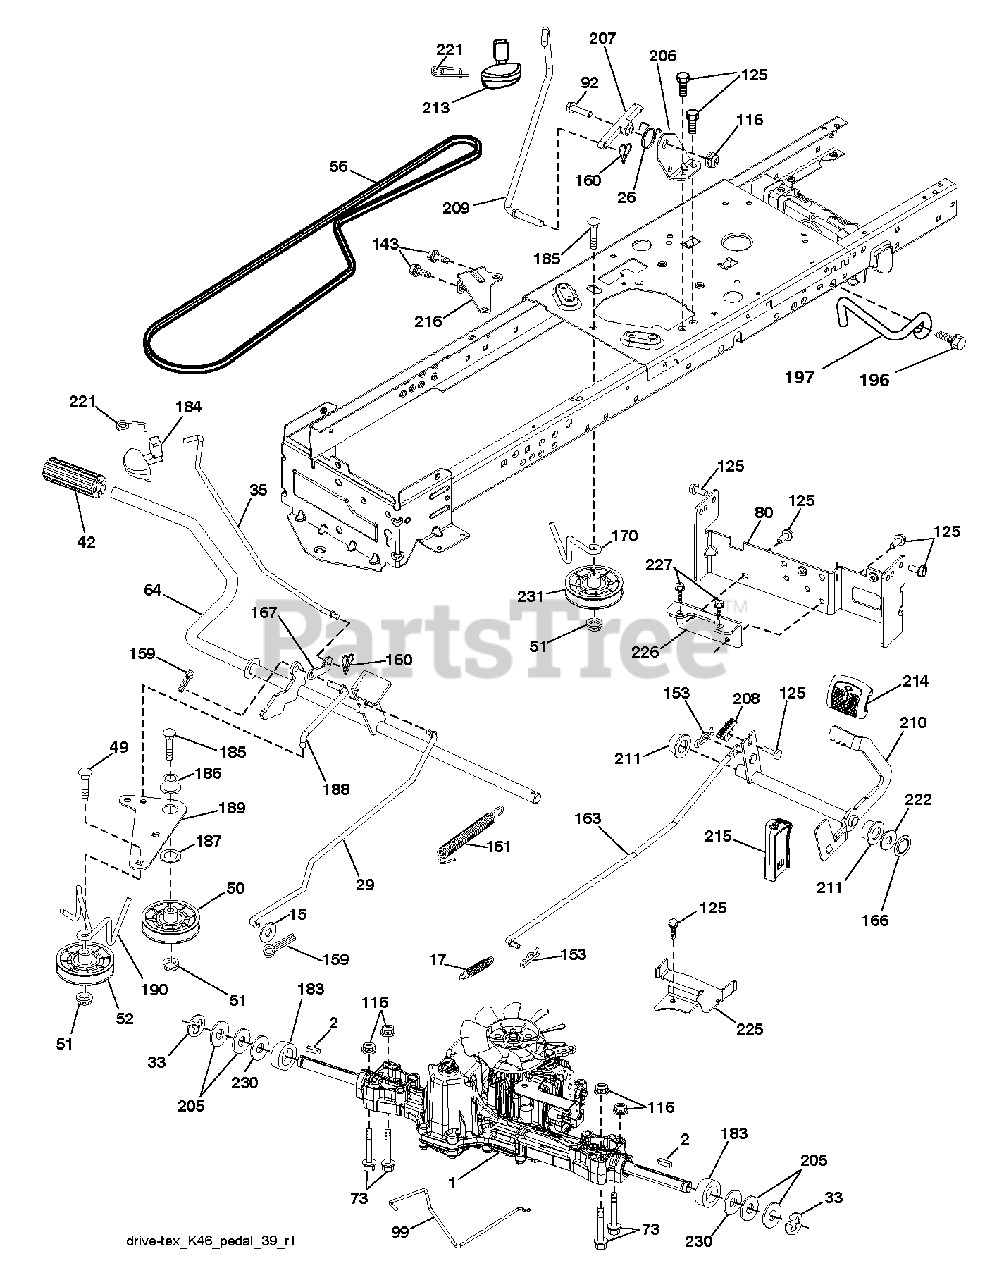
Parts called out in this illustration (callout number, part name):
2	SQUARE KEY
15	WASHER
17	SPRING.BRAKE.K46.GREEN
26	SPRING.RETURN.CRUISE
29	ROD.BRAKE.K46
33	E-RING LT
35	ROD.BRKAE.PARKING.STEALTH
50	IDLER.FLAT.910.OFFSET
52	IDLER.V-GROOVE.910.OFFSET
64	SHAFT.ASM.PEDAL.BRK.CN
80	STRAP TORQUE
99	ROD.SPRING.BYPASS.K46.LT.Z
116	NUT LOCK HEX FLANGE 5/16-18
143	SCREW LT
159	COTTER PIN
160	RETAINER CLIP
161	SPRING, RETURN LT
163	ROD.CONTROL.PEDAL.K46
166	NUT.PUSH.625
167	LATCH BRAKE PARKING
170	KEEPER.CENTER SPAN.1.688
183	SPACER AXLE
184	HANDLE.PRKG.BRAKE.STLTH.TX505
186	SPACER.RETAINER
188	LINK.CLUTCH.GROUND DRI
189	BELLCRANK.GRDDRIVE.NST
190	KEEPER.BELLCRANK.DRIVE
196	SHAFT ASSY
197	LINK.CLUTCH.ANIT-ROTAT
206	BRKT.MOUNT.LATCH.CRUIS
207	LATCH.CONTROL.CRUISE
208	GEAR.SECTOR.CONTROL.CR
209	ROD.CONTROL.CRUISE.STE
210	ROCKER.ASM.PEDAL.CONTR
211	BEARING NYLON
213	KNOB.CONTROL.CRUISE
214	PAD PEDAL FORWARD
215	PEDAL.REVERSE.TEX.GT.4
216	BRKT.PULLEY.IDLER.WTEX
221	RETAINER.SPRING.CLIP.H
222	WASHER 21/32 X 1-1/4 X 10 GA.
225	KEEPER.BELT.TRANSAXLE.
226	BRACKET MOUNT TORQUE
231	PULLEY VGROOVE
